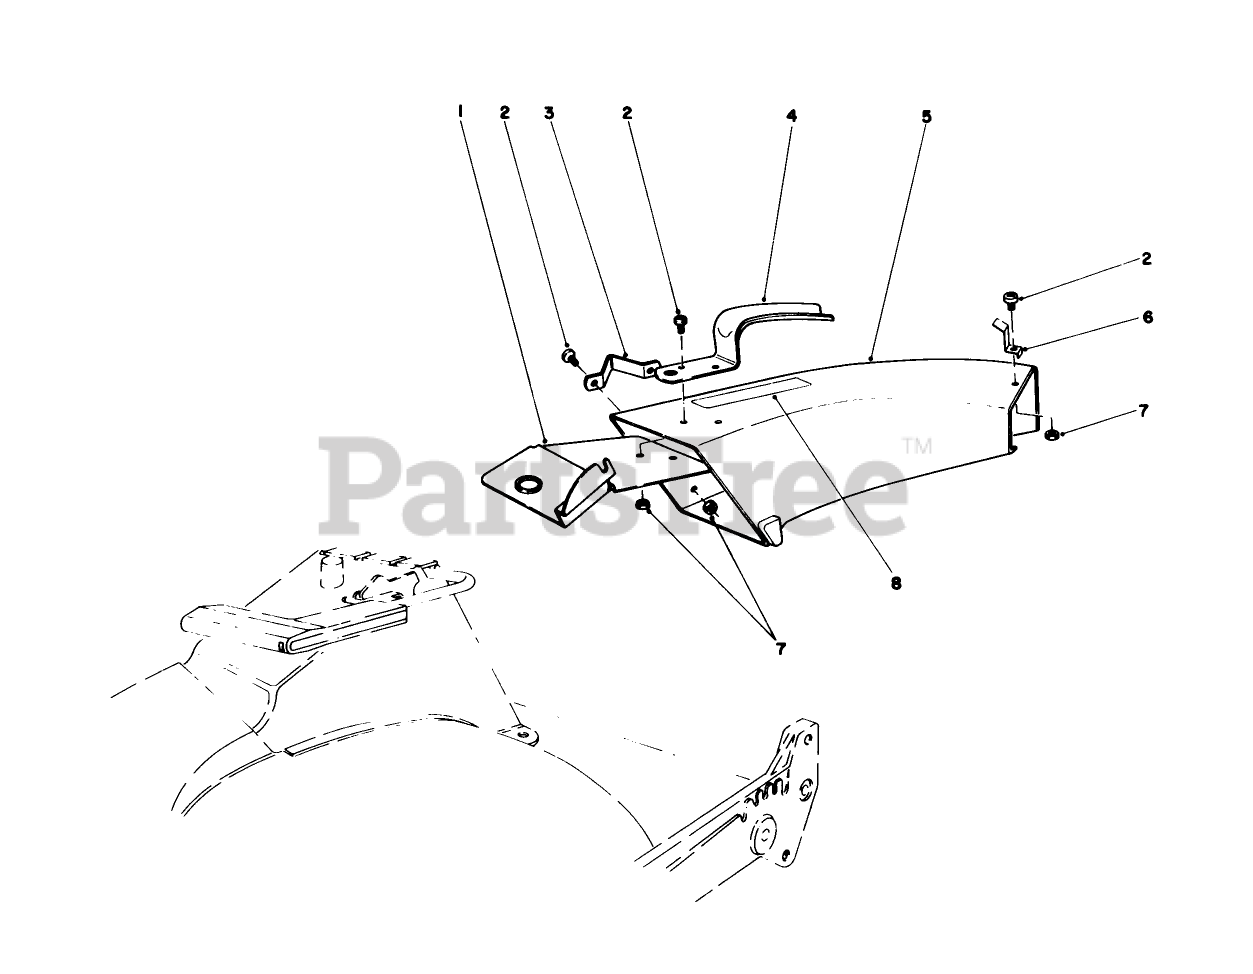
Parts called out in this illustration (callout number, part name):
2	10-24 X 5/8 PAN HD MS
4	CHUTE HANDLE
5	ORDER 59168 W.G.#
7	NUT-LOCK, NI
